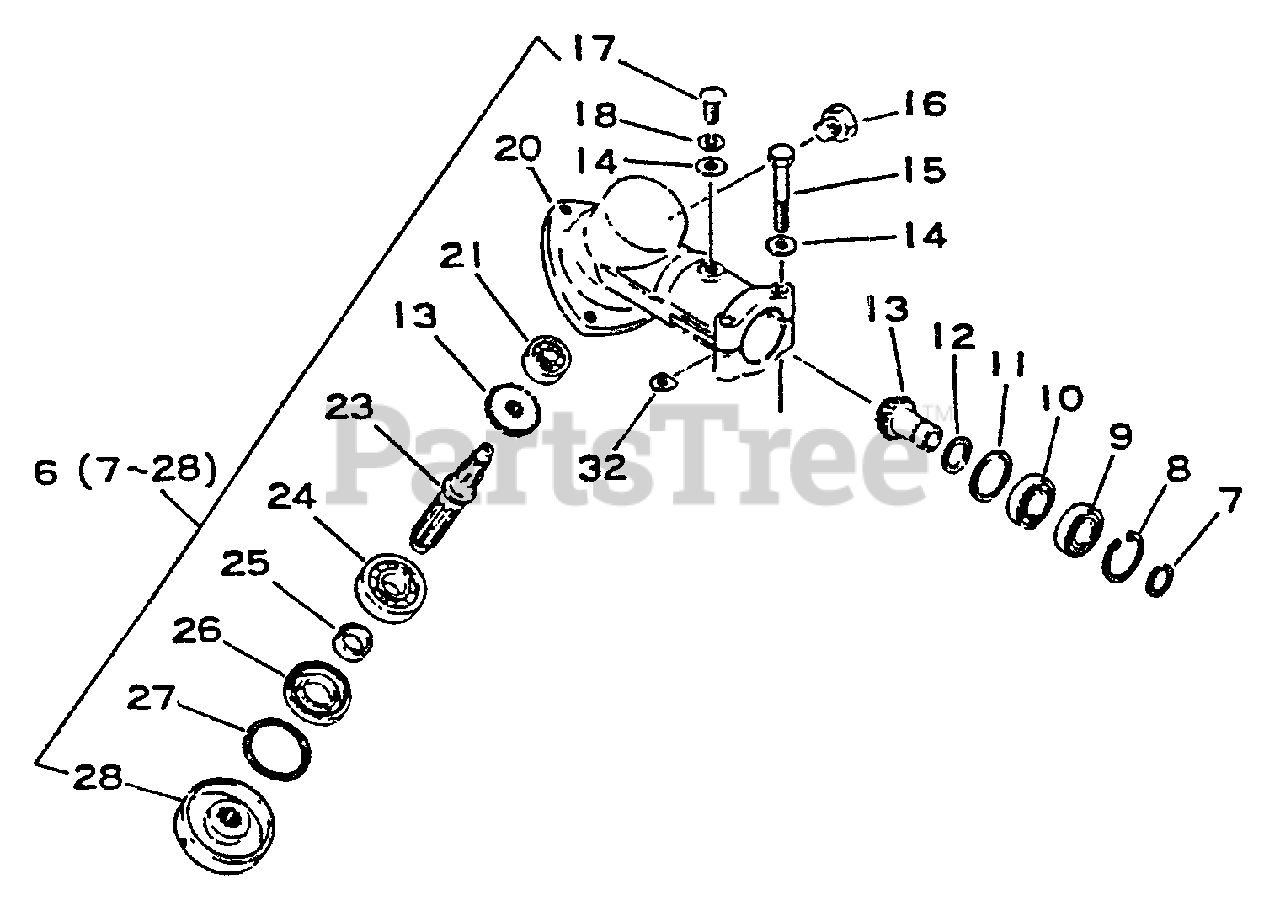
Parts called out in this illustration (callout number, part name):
6	GEAR CASE ASSY
7	RING, SNAP Ø10
8	RING, SNAP Ø22
9	BEARING, BALL 6900Z
10	BEARING, BALL 6900
13	GEAR SET
14	WASHER, FLAT 5.5×10×0.8
15	BOLT 5×35 SP
16	BOLT 8×8 SP
17	SCREW 5×10
18	WASHER, SPRING 5
20	CASE, GEAR
21	BEARING, BALL 626
23	SHAFT, GEAR
24	BEARING, BALL 6000
26	SEAL, OIL
27	RING, SNAP 26
28	PLATE, ADAPTER - UPPER
